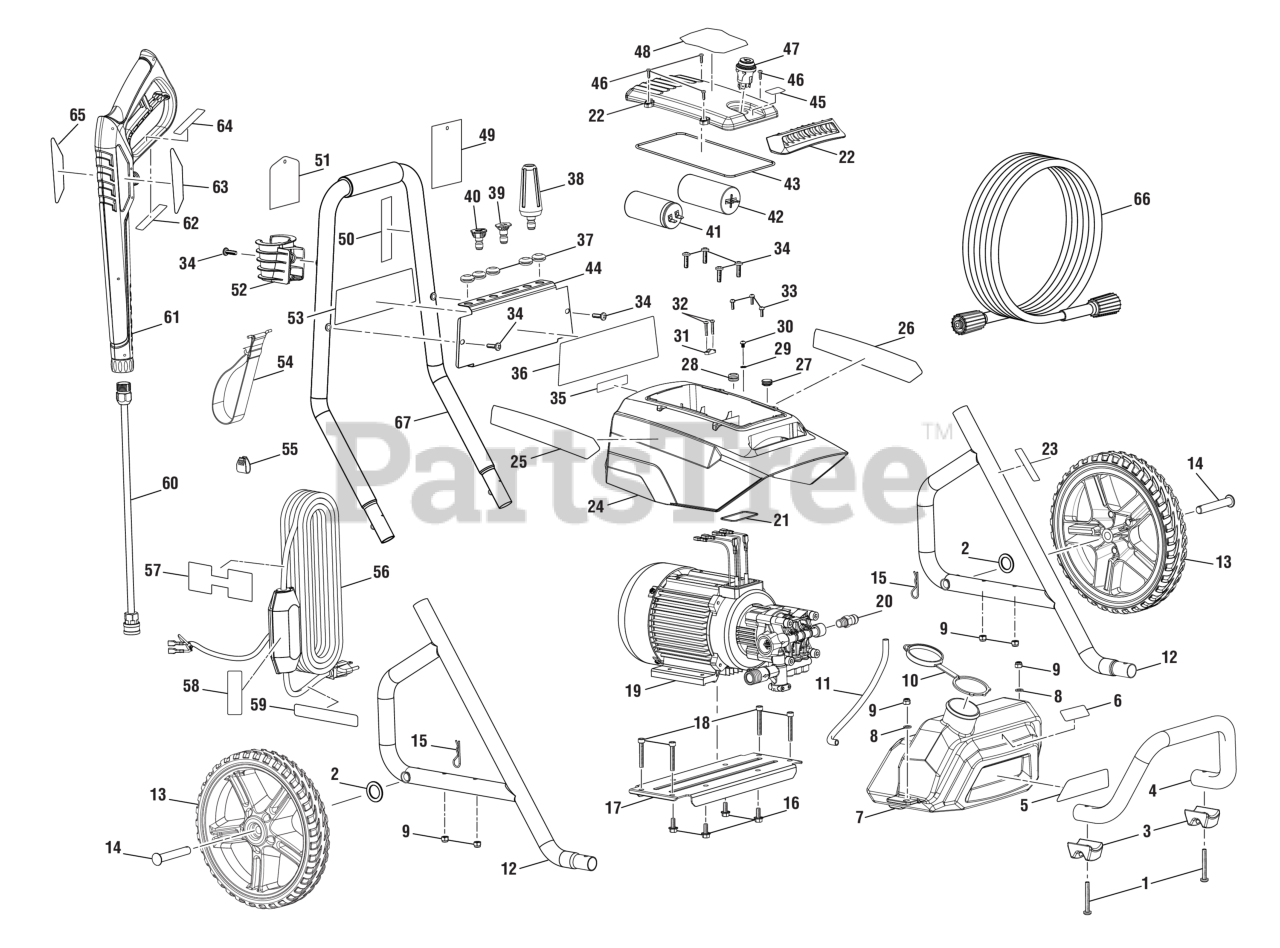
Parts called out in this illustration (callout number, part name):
1	Screw (M6 x 1 x 48 mm, T30 Torx Pan Hd.)
2	Washer (OD21 x 14 x 1t)
3	Rubber Foot
4	Frame Assembly (Front)
5	Detergent Tank Logo Label
6	Detergent Tank Label
7	Detergent Tank
8	Washer (OD12 x ID6.6 x 1.6t)
9	Lock Nut (M6)
10	Soap Tank Cap
11	Detergent Injection Hose
12	Frame Assembly
14	Wheel Axle
15	Cotter Pin
16	Flange Bolt (M6 x 1 x 16 mm, Hex Hd.)
17	Motor Plate
18	Bolt (M6 x 40 mm, Socket Hex Hd.)
20	Thermal Release Valve.
21	Wire Box Gasket (Lower)
22	Upper Housing Assembly
23	Warning Label (Inquiries)
24	Motor Shroud
25	Beauty Wing Label (Right)
26	Beauty Wing Label (Left)
27	Water Seal
28	Soap Tank Grommet
29	Toothed Lock Washer (M4)
30	Screw (M4 x 16 mm, Pan Hd.)
31	Cord Clamp
32	Screw (M3.5 x 20 mm, Button Hd.)
33	Bolt (M4 x 12 mm, Pan Hd.)
34	Bolt (M6 x 20 mm, Philips Pan Hd.)
35	Try Another Outlet Label
36	Performance Label
37	Rubber Nozzle Grommet
38	Turbo Nozzle
39	Soap Nozzle (Blue)
40	15deg Nozzle
41	Capacitor (CD60 250 VAC 300UF)
42	Capacitor (CBB60 SH PO 250 VAC 120UF)
43	Rubber Gasket
44	Face Panel
45	On/Off Label
46	Screw (M4.2 x 15 mm, Phillips Hd. S.T.)
47	On/Off Switch
48	Brushless Label
49	Danger Hangtag (Spanish)
50	Quick Start Label
51	Nozzle Hangtag (PS141913)
52	Handle Holder
53	Danger Label
54	Hose Holder Strap
55	Electric Cord Clip
56	Power Cord Assembly
57	Cordwrap Warning Label
58	Power Cord Label
59	Outlet Cord Wrap Label
60	Spray Wand Assembly
61	Trigger Handle
62	Rating Label
63	Trigger Handle Warning Label (English)
64	Label (Trigger Handle Warning, French & Spanish)
65	Trigger Handle Logo Label
66	High Pressure Hose
67	Handle Assembly
